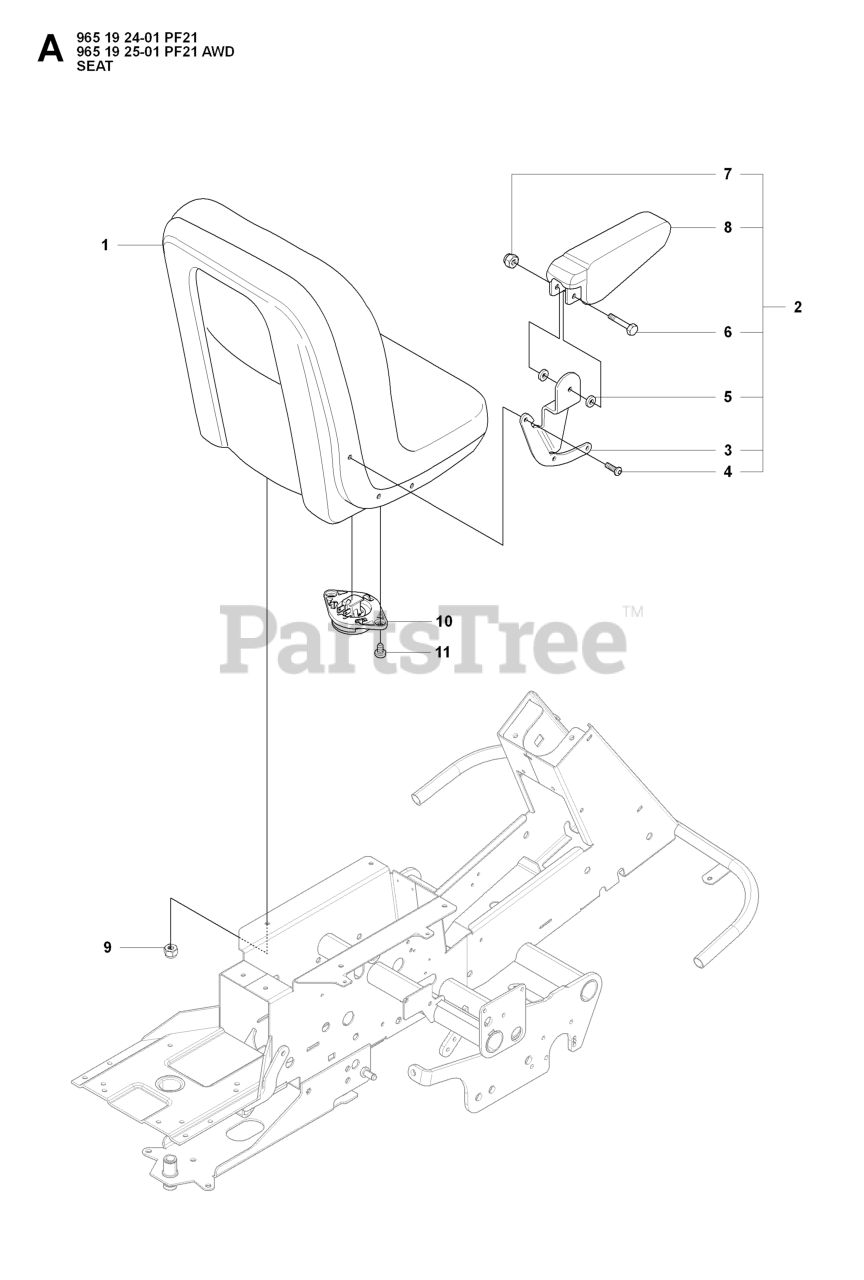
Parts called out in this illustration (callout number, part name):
9	LOCKNUT M8
10	ANTI-START SWITCH CPL
11	SCREW
